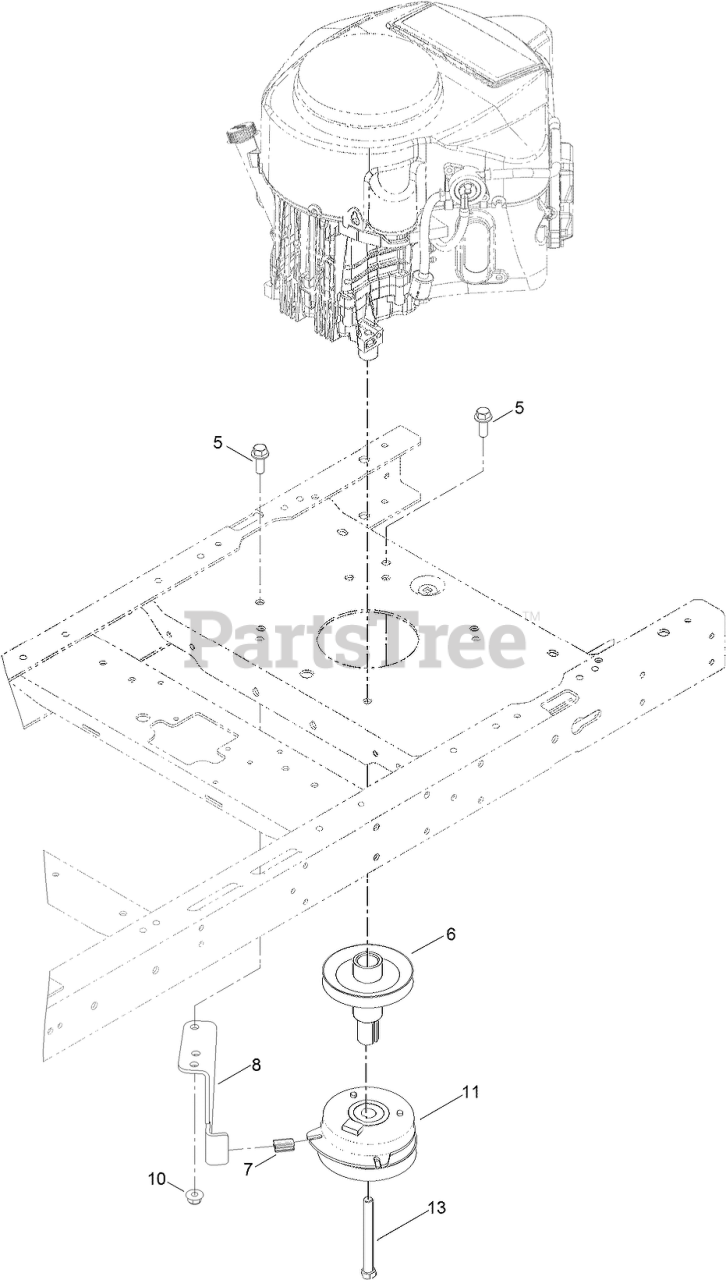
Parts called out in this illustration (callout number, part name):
5	SCREW-HHF
6	PULLEY-ENGINE
7	ISOLATOR-CLUTCH
8	STOP-CLUTCH
10	NUT-HF, NI
11	CLUTCH-PTO
13	Screw-HH
